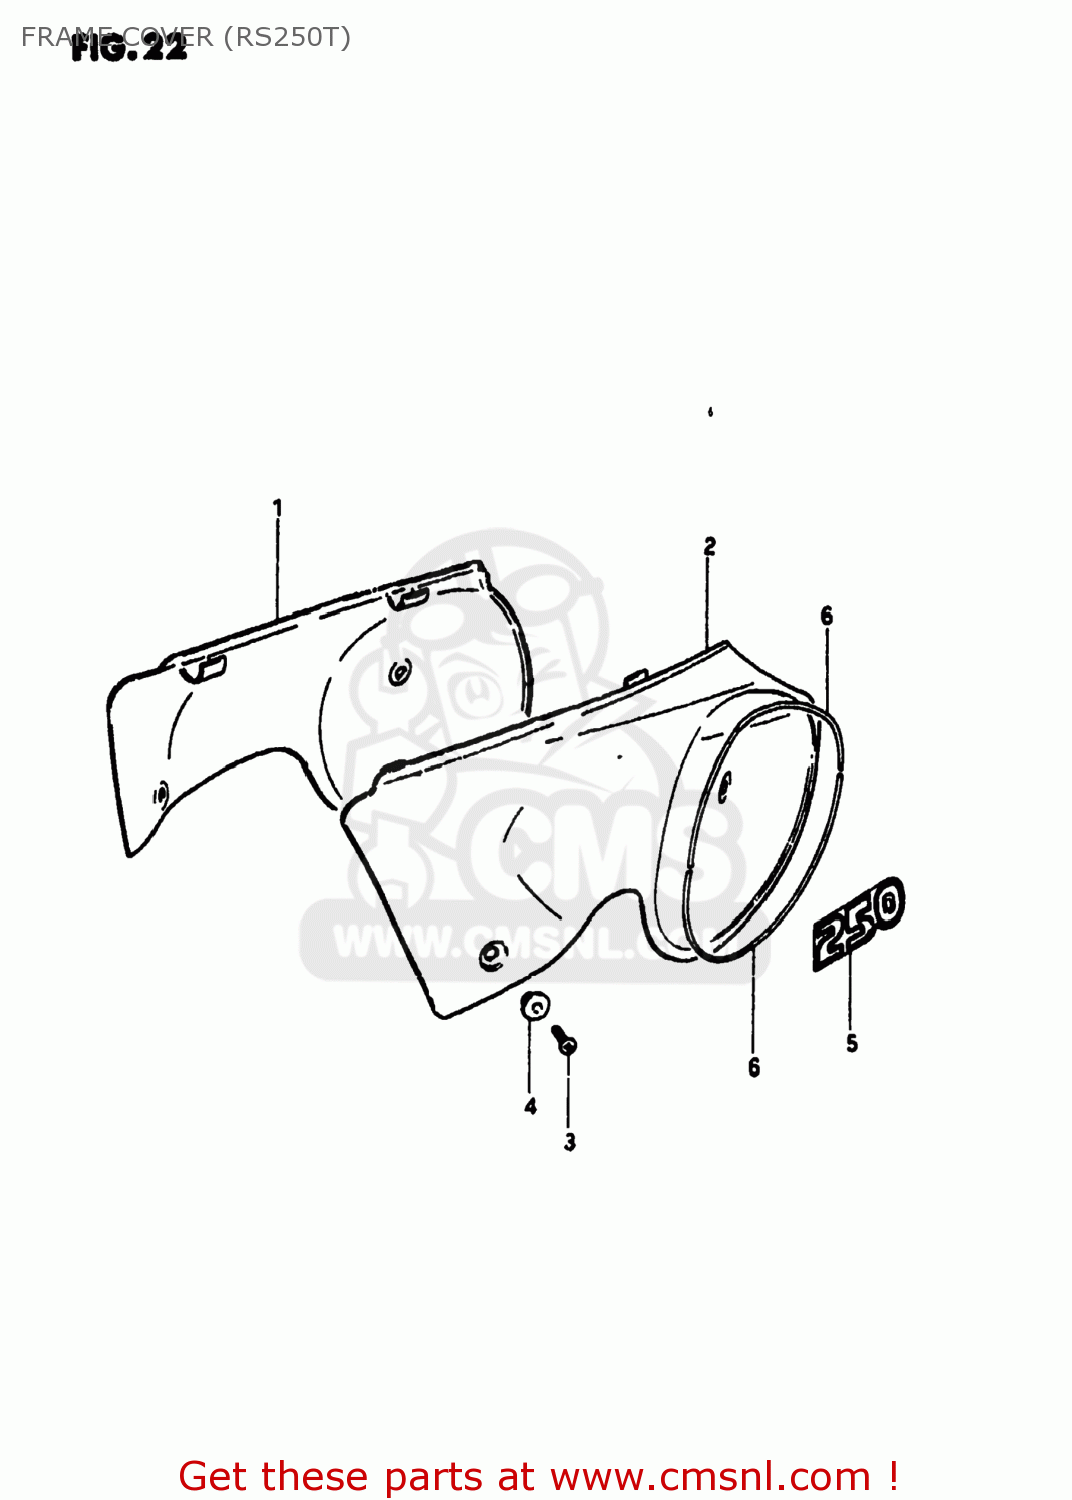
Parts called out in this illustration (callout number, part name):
1	COVER,FRAME,R(YELLOW)
2	COVER,FRAME,L(YELLOW)
3	SCREW 6X12
4	WASHER
5	EMBLEM
6	TAPE,FRAME COVER
